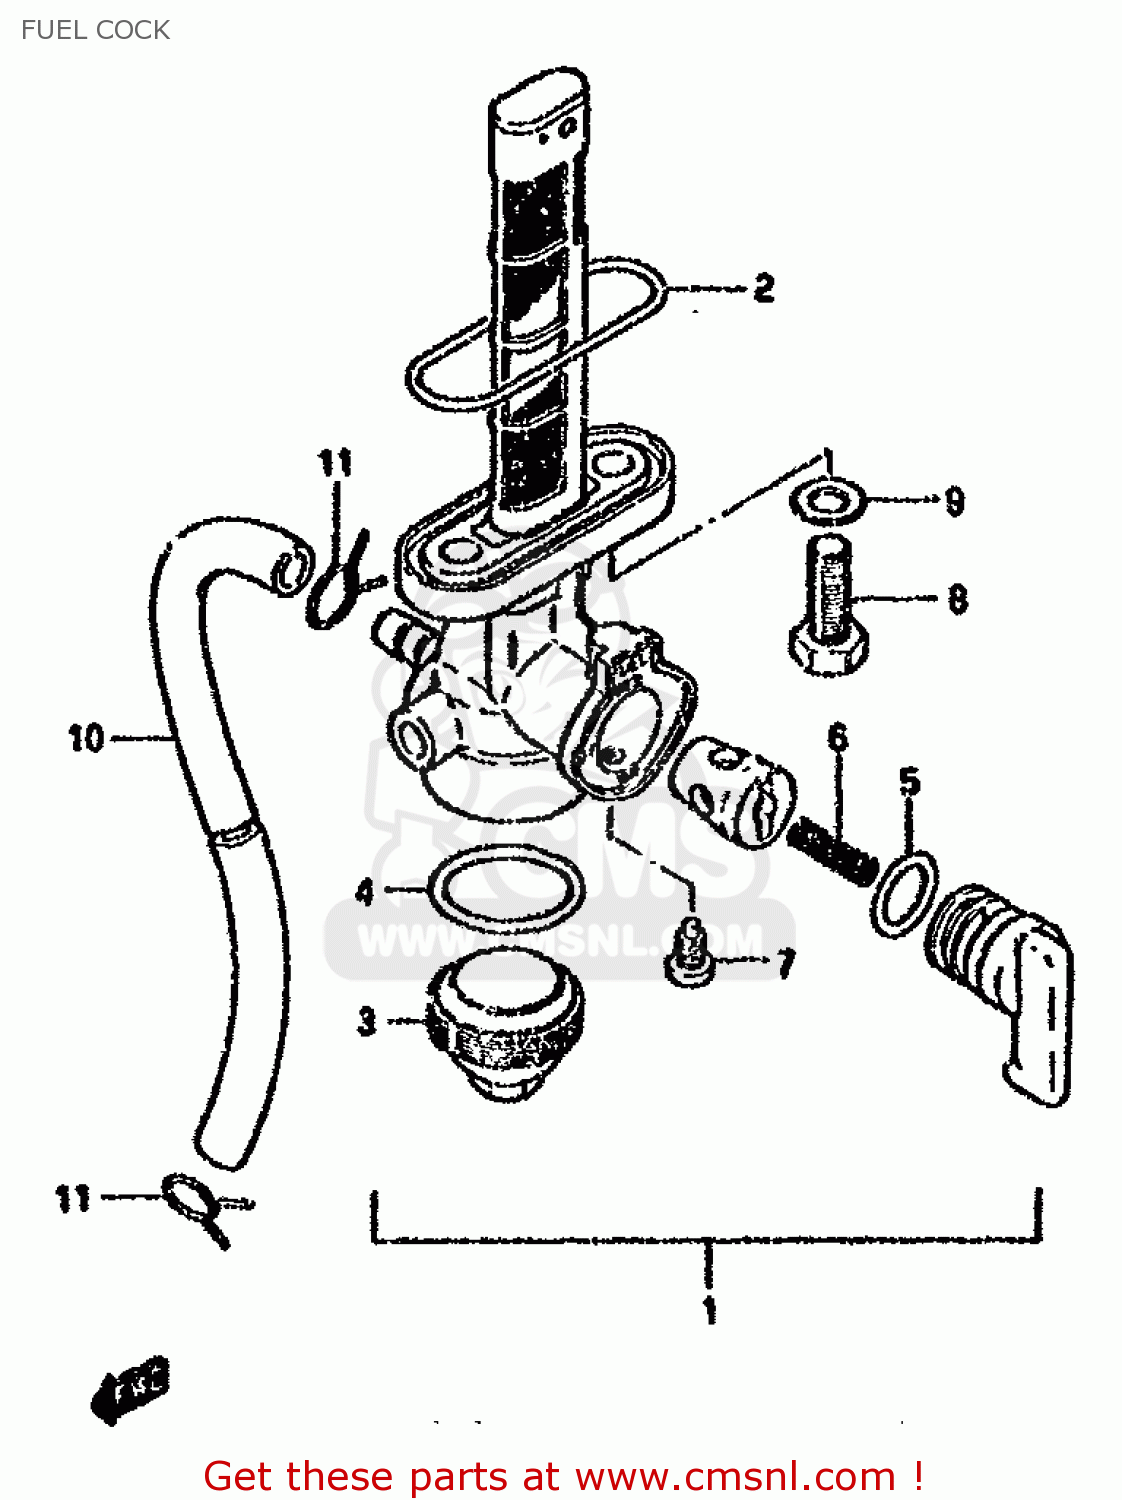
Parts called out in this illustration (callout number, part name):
1	COCK ASSEMBLY,FUEL
2	O RING,FUEL COCK
3	CUP,STRAINER
4	GASKET,FILTER (NAS)
5	O-RING,LEVER
6	SPRING
7	SCREW
8	BOLT(6X20)
9	GASKET(6.4X11.5X0.8) (NAS)
10	HOSE
11	CLIP
